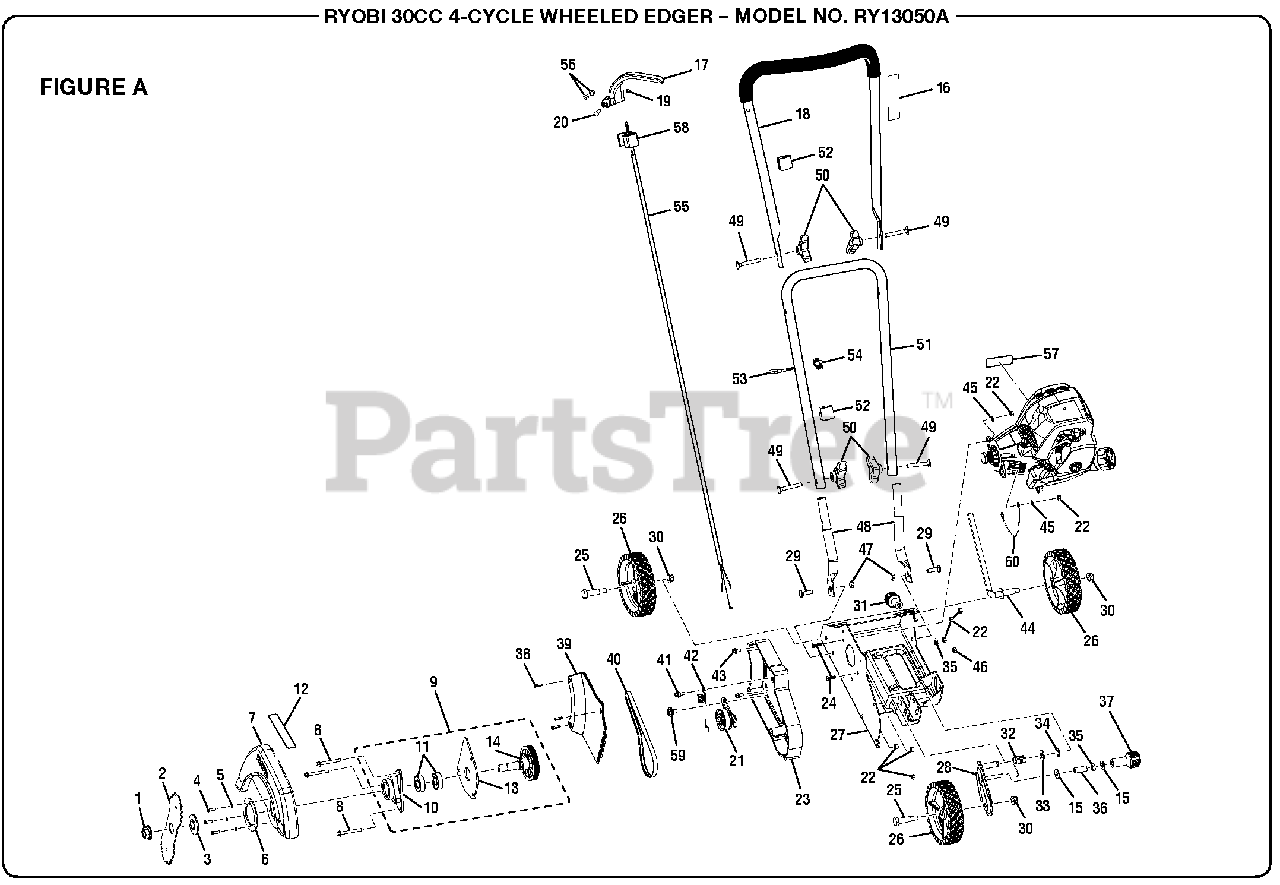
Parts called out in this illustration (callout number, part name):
1	Blade Nut (M16, Flanged)
2	Edger Blade
3	Flanged Washer
4	Screw (10-24 x 5/8 in, Hex Hd.)
5	Lock Washer (5mm)
6	Ring Washer
8	Bolt (M6 x 55 mm)
9	Front Pulley Assembly
10	Bearing Plate
11	Ball Bearing (6203-2RS)
12	Warning Label (Guard)
13	Mounting Plate
14	Blade Shaft and Pulley Assembly
16	Warning Label (Upper Handle)
18	Upper Handle Assembly
20	Pivot Pin
21	Idler Pulley Assembly
22	Lock Nut (M6)
23	Guard Cover Base
24	Screw (M6 x 20 mm)
25	Shoulder Bolt (M10 x 34 mm)
26	Wheel Assembly (6 in.)
27	Edger Base w/Bushings
28	Front Wheel Bracket Assembly
29	Handle Bar Bolt (M8)
30	Lock Nut (M10, Flange)
31	Axle Spring
32	Front Axle Spring
33	Washer (M13)
35	Lock Washer (M8)
36	Front Axle Bushing
37	Wheel Adjuster Knob
38	Bolt (M6 x 16 mm, Thread Forming)
39	Belt Cover
41	Shoulder Bolt (M6 x 17 mm)
42	Idle Pulley Spring
43	Bolt (M6 x 12 mm)
44	Bracket Assembly
45	Washer (6 mm)
46	Hex Nut (M8)
47	Flange Nut (M8)
48	Handle Post
49	Carriage Bolt (M8 x 60 mm)
50	Knob Assembly
51	Lower Handle
52	Cable Clip
53	Hook Screw (M5 x 18 mm)
54	Wing Nut (M5)
55	Throttle Cable Assembly
56	Plastic Washer
57	Warning Label (Combustion)
59	Shoulder Bolt (M8)
60	Ground Wire
